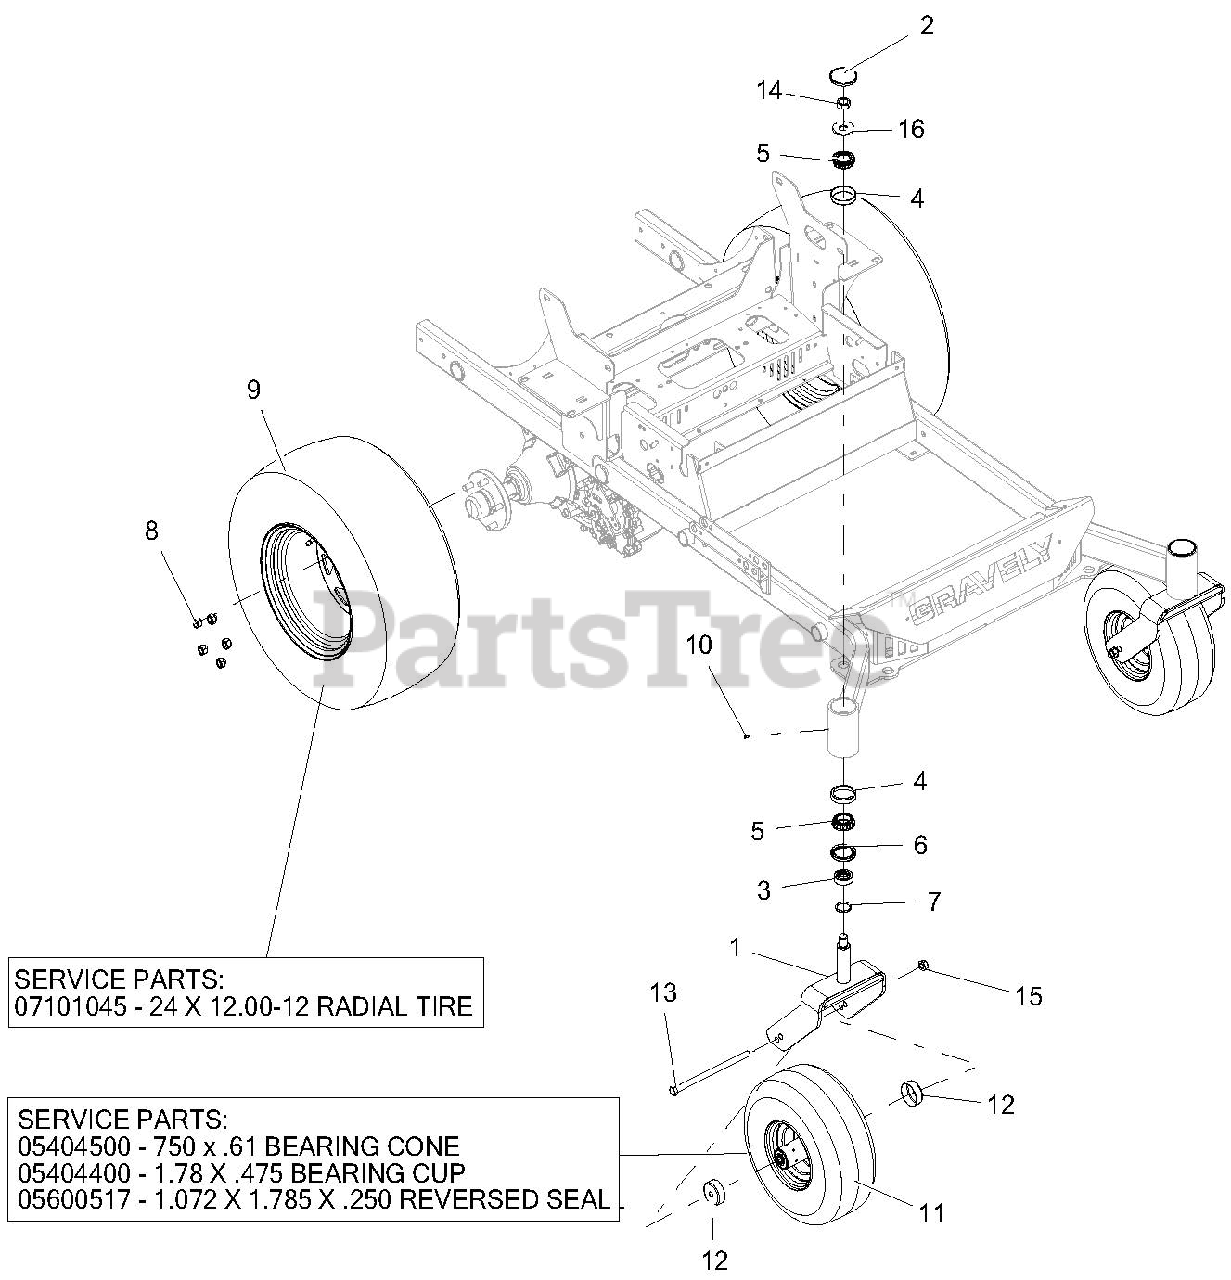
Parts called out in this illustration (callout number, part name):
1	WMT, CASTER FORK - RED
2	CAP, DUST
3	SPCR, FRONT CASTER FORK
4	BRG, CUP 2.328 X .465
5	BRG, CONE 1.250 X .660
6	SEAL, OIL 1.75 X 2.332 X .312
7	O-RING, .139 W X 1.234 ID
8	NUT, LUG .500-13
9	TIRE/WHEEL, ASM 24 X 12-12 RADIAL
9	24 x 12.00-12 RADIAL TIRE
10	FITTING, .250-28 FLUSH MOUNT GREASE
11	TIRE/WHEEL, 15 X 6.00-6 SEMI-PNEU
11	750 X .61 BEARING CONE
11	1.78 X .475 BEARING CUP
11	1.072 X 1.785 X .250 REVERSED SEAL
12	SHIELD, WHEEL BEARING
13	BLT-HEX .50-13X9.00 GR5 YWZC
14	@NUT-LK-TOP-JAM .75-16 YWZC
15	NUT, LK-TOP-FLG .50-13 YWZC
16	WSHR-FL-STL.812X2.00X.148YWZC
